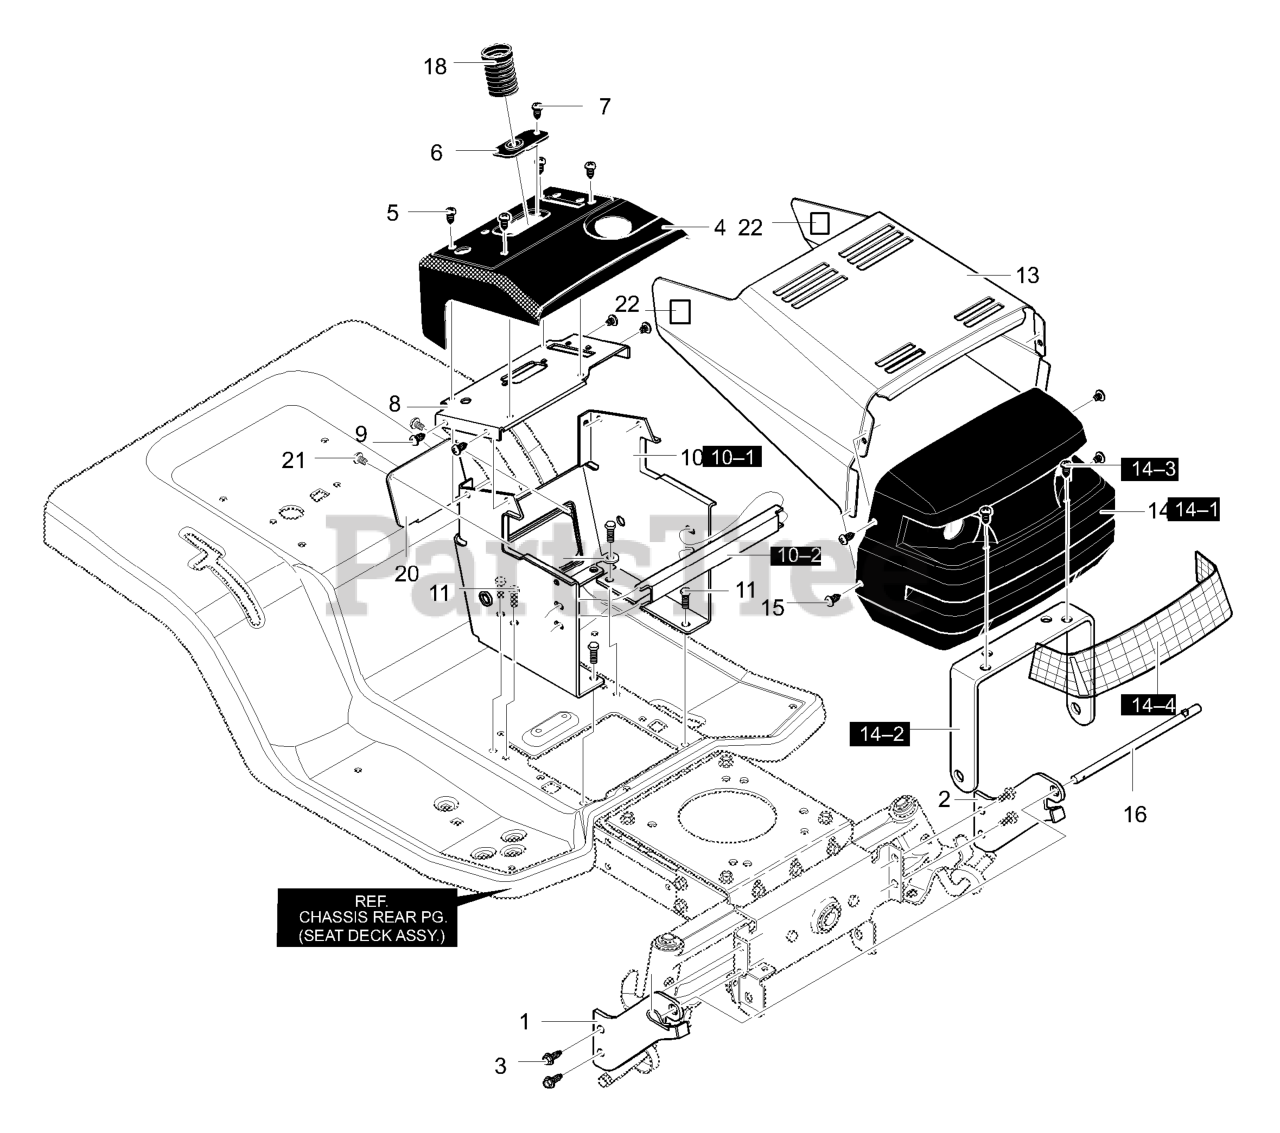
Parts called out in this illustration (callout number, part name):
1	BRACKET, RIGHT GRILLE
2	BRACKET, LEFT GRILLE
6	BEARING
8	PLATE, DASH PANEL
10	LOWER CONSOLE SUPPORT
14	ASSEMBLY, GRILLE
16	ROD, HOOD PIVOT
17	PIN, HAIR
18	BELLOWS, STEERING
19	WASHER
20	ACCESS PANEL
22	PAD, ADHESIVE
